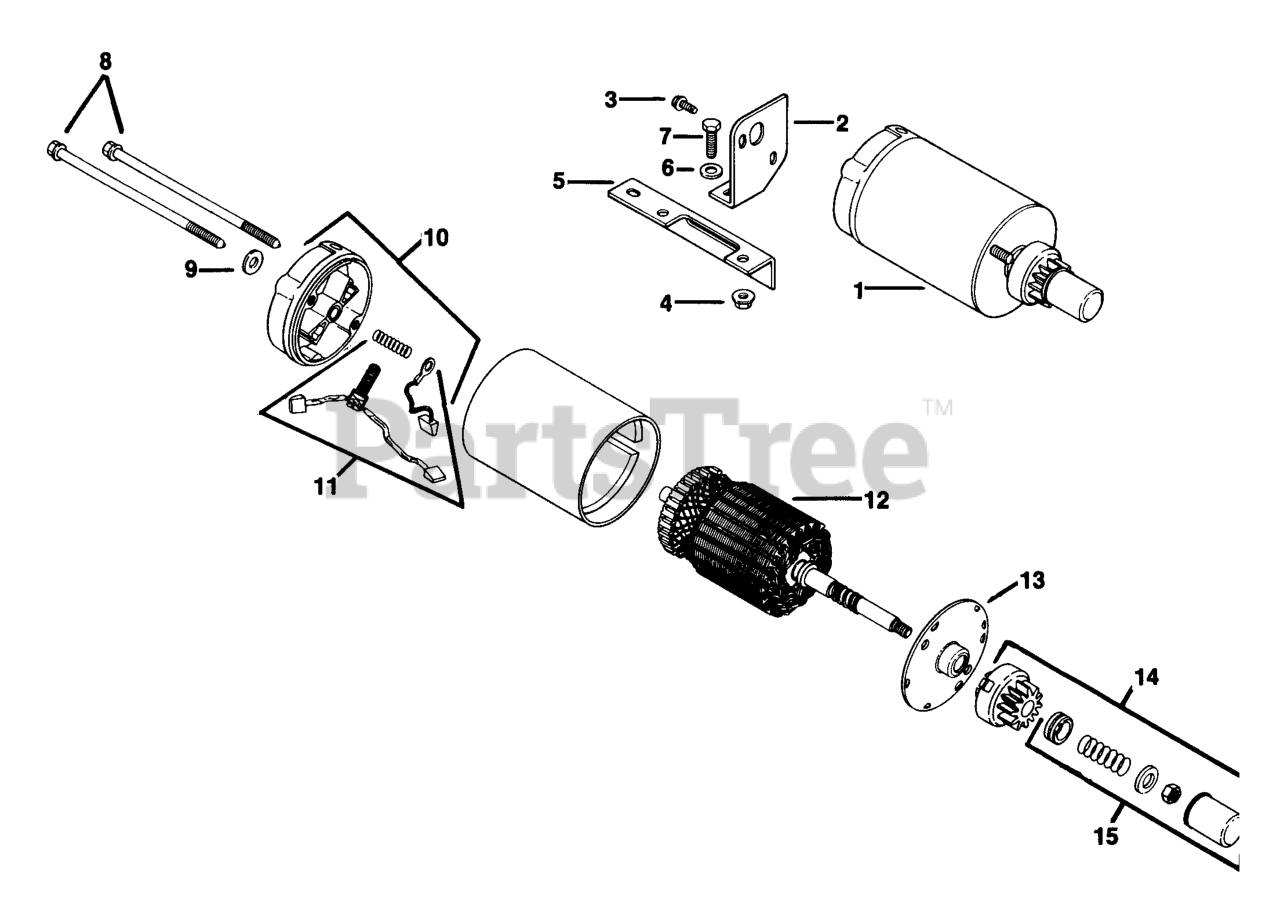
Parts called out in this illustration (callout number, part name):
1	STARTER - USE 41 098 06
3	SCREW, WSH HD TAP 1/4-20X3/4" USE 25 086 100-S
4	PALNUT, 1/4-20
6	WASHER, FLAT 1/4" (O.D. 5/8")
7	SCREW, CAP HD 1/4-20x5/8"
8	BOLT, STARTER 1/4-20X5-1/16"-(#DSC)
9	WASHER, FLAT 1/4" (O.D. 5/8")
10	CAP - USE 52 227 03
11	KIT - USE 82 755 28
12	ARMATURE - DISCONTINUED
13	CAP - USE 41 081 05
